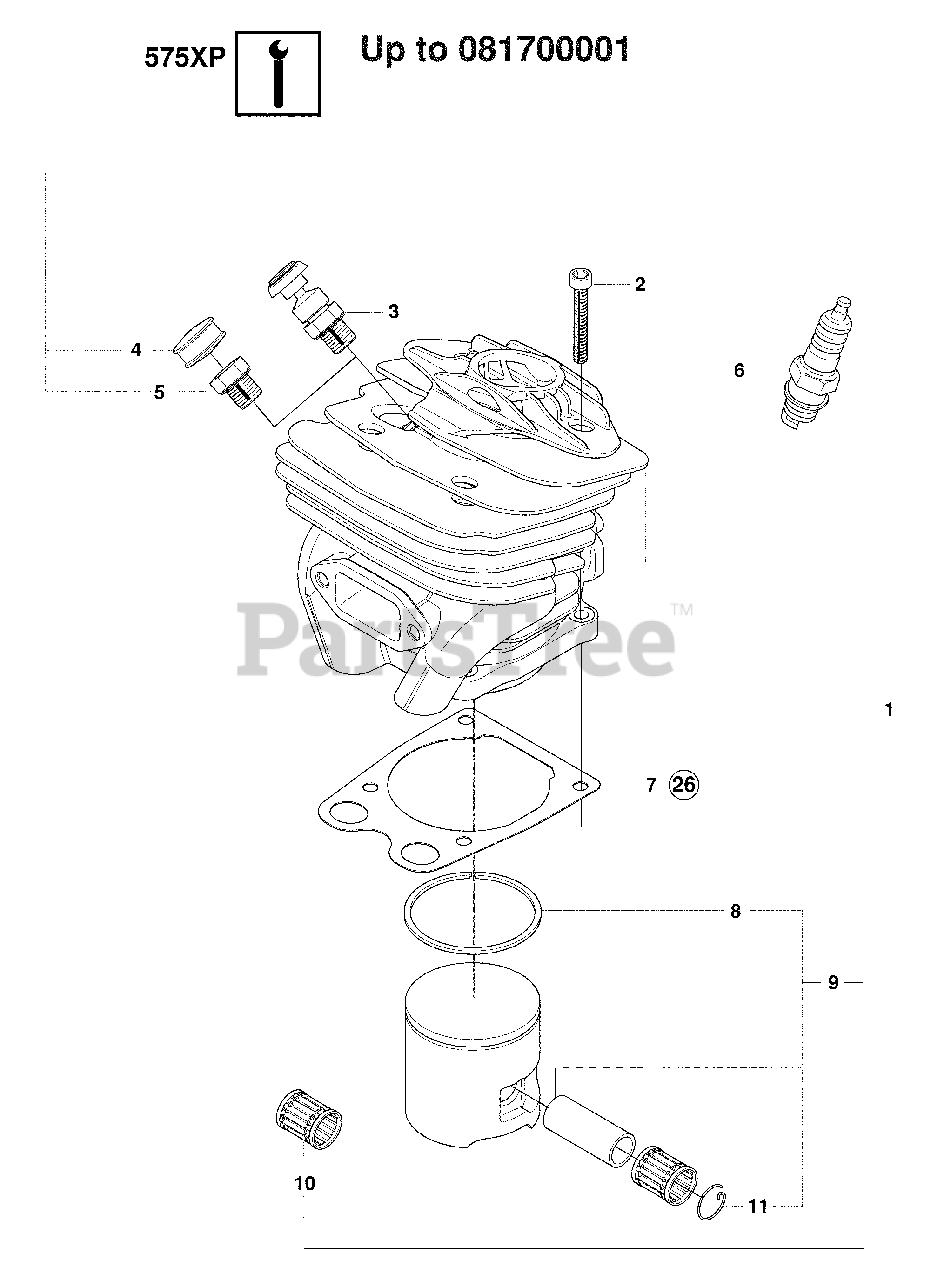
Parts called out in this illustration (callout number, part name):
1	Cylinder
2	Screw, MC6S 5 X 25
3	Valve
5	Cylinder Plug
6	Solid Spark Plug, BPMR7A
8	Piston Ring
9	Piston, 49mm
10	Needle Bearing Piston Pin, 12 X 1
26	Gasket Set
